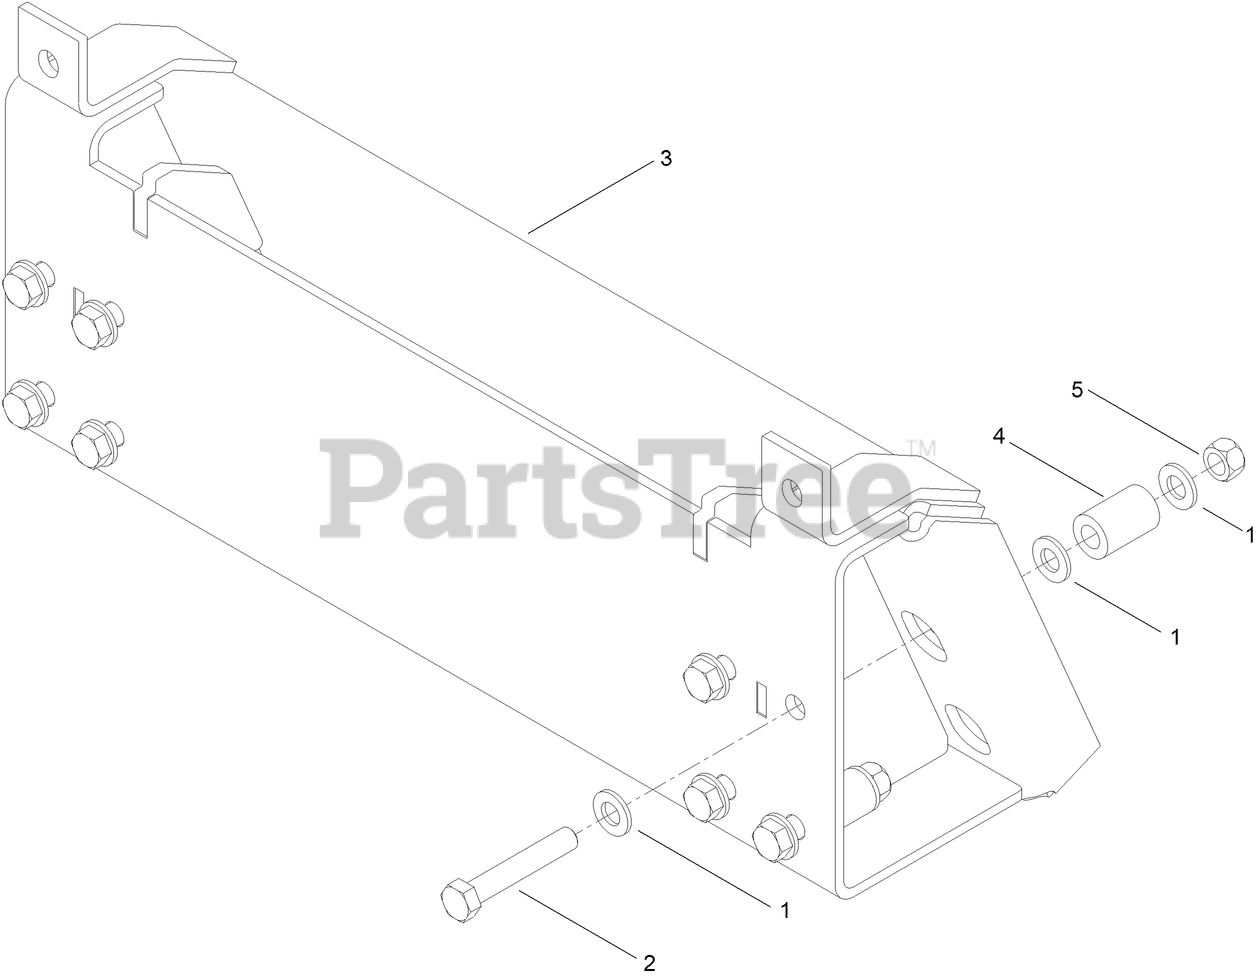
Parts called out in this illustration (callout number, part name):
1	WASHER-FLAT
2	SCREW-HH
3	PLATE-ATTACHMENT
4	SPACER-ATTACHMENT, PLATE
5	NUT-HEX
